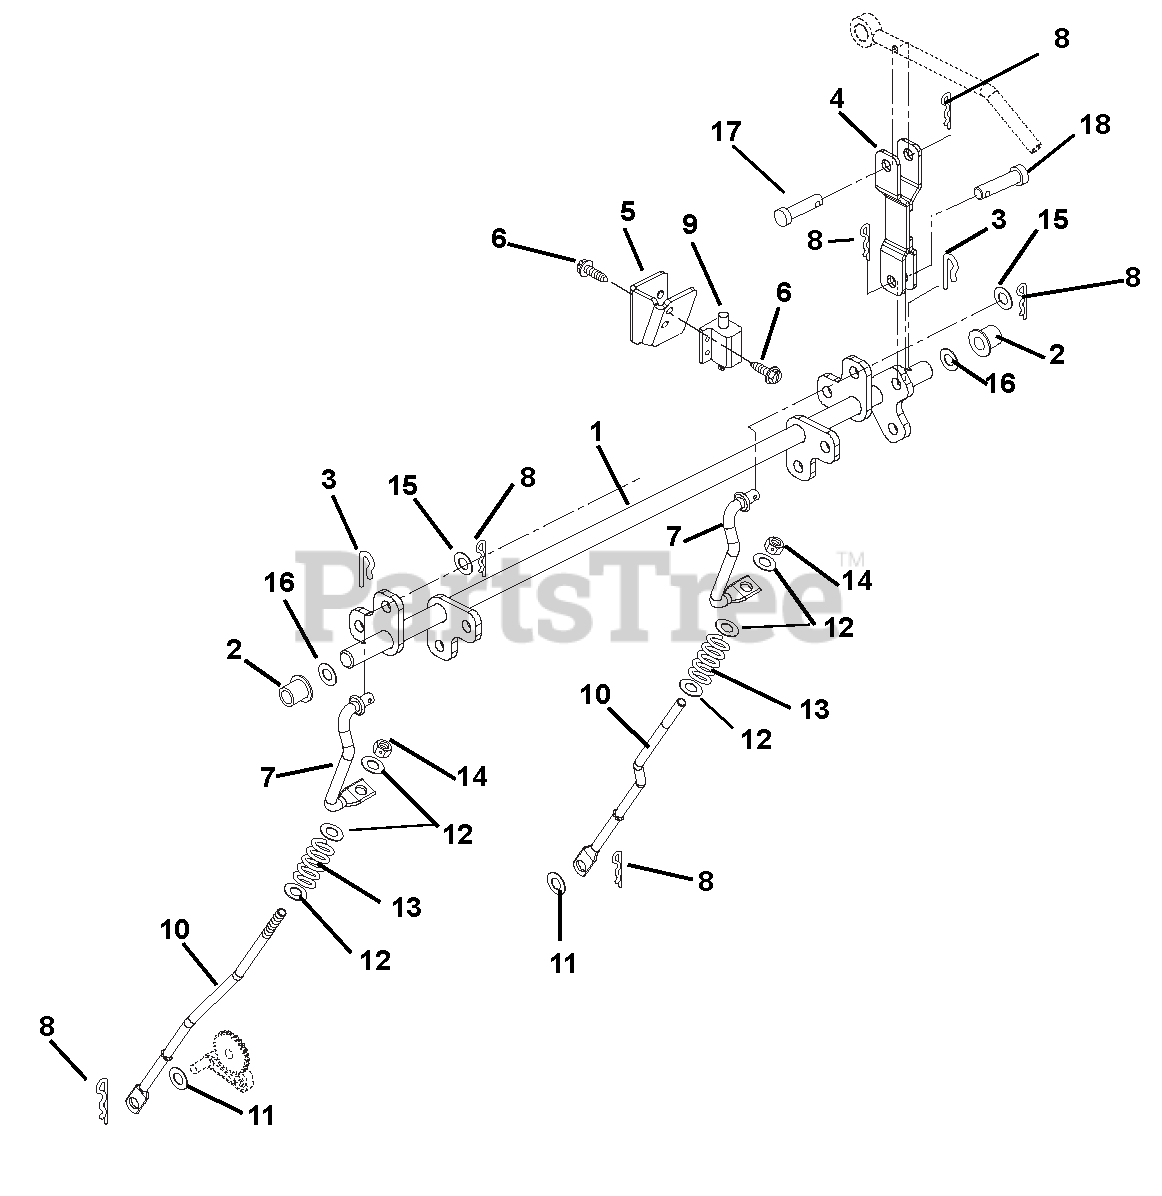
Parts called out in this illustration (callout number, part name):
1	WMT, BRAKE ROD
2	BSHG-FLG .630X1.000X.625 NY
3	PIN, SPRING CLIP
4	CLEVIS WELDMENT
5	BRACKET, BRAKE SWITCH
6	@SCR-TAP 10-24X.50 HWH TR YWZC
7	ROD-OVER CENTER
8	PIN-HAIR, ENDRIES #25 YWZC
9	SWITCH- DOUBLE POLE N.O./N.O.
10	ROD, PARK BRAKE IZT
11	WSHR-FL-STL .406X1.00X.188 YWZ
12	@WSHR-FL-STL.344X.688X.065YWZC
13	SPRING, COMPRESSION
14	@NUT-LK-NYL .312-18 YWZC
15	@WSHR-FL-STL.406X.812X.065 YWZ
16	WSHR-FL-STL .627X.990X.032
17	PIN-CLEV .370X1.50
18	PIN-CLEV .375X.948 YWZC
